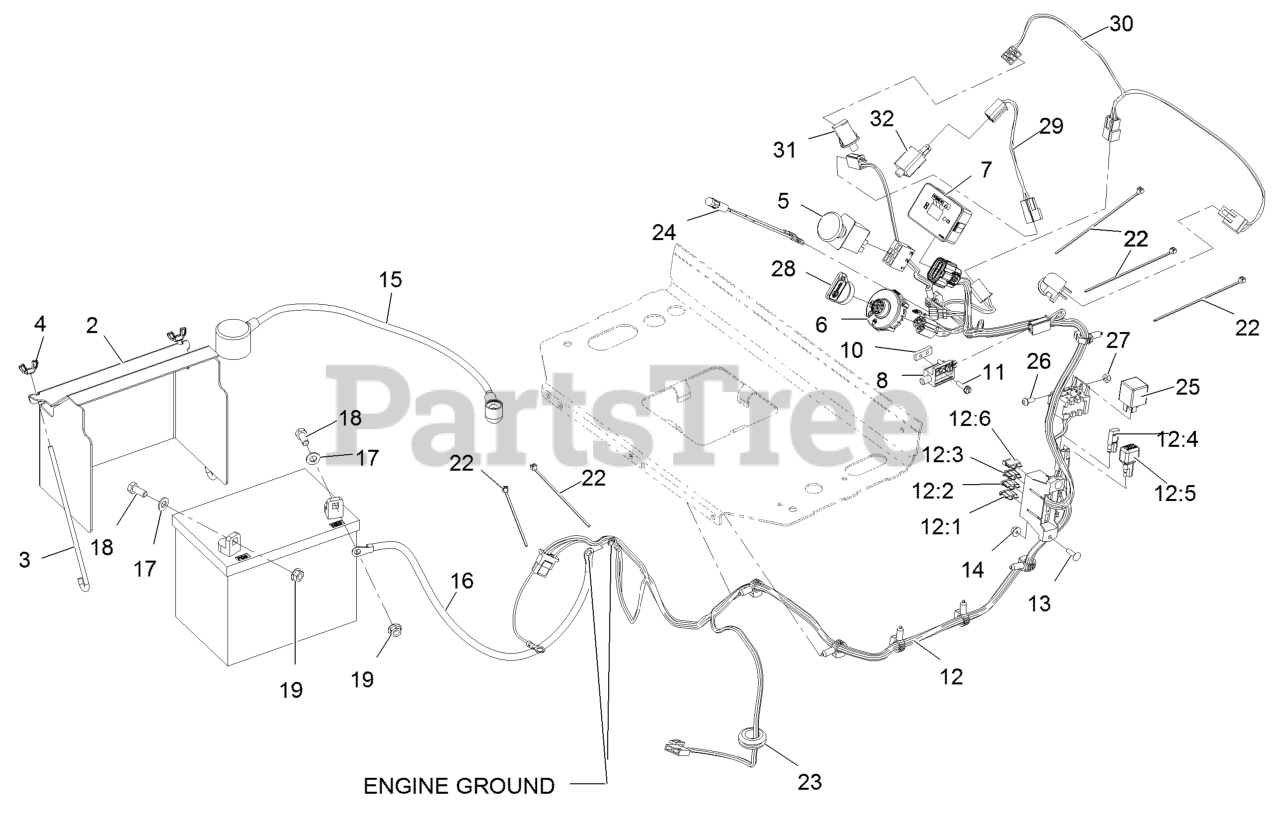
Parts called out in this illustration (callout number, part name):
2	COVER-BATTERY
3	BOLT-HOLDDOWN
4	WINGNUT
5	SWITCH-PTO, ON-ON
7	MODULE-HOUR METER
8	SWITCH-CLOSED, NORMALLY
10	PLATE-TAPPED
11	SCREW-HWH
12	HARNESS-WIRE, EFI
12:1	FUSE-BLADE, 30 AMP
12:2	FUSE-BLADE, 25 AMP
12:3	FUSE-BLADE, 10 AMP
12:6	FUSE-BLADE, 15 AMP
13	SCREW-CARR
15	CABLE-BATTERY, POSITIVE
16	CABLE-BATTERY, BLACK
17	WASHER-PLAIN
18	SCREW-HH
19	NUT-HHF, SMOOTH
22	TIE-CABLE
23	GROMMET
24	INDICATOR-LED, RED
26	SCREW-PPH
27	NUT-LOCK, NI
28	KEY-IGNITION
29	HARNESS-NEUTRAL
30	HARNESS-OPC
31	SWITCH-BAIL
32	SWITCH-OPEN, NORMALLY
